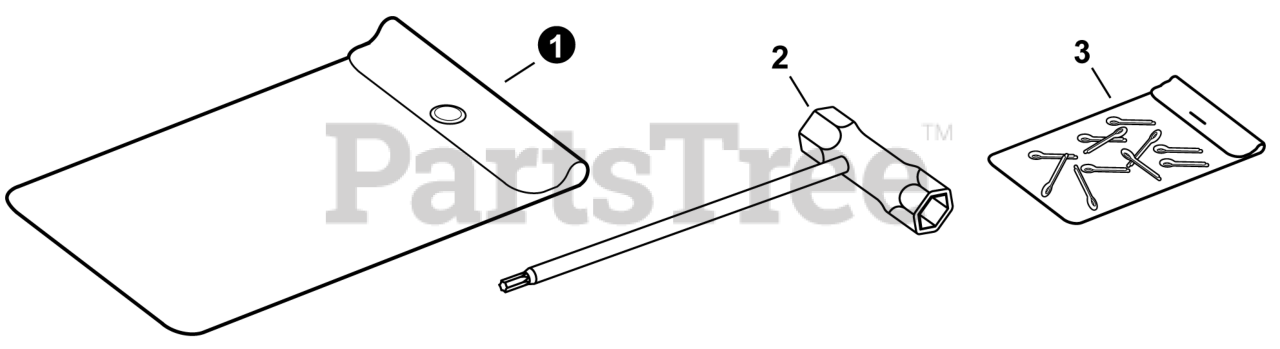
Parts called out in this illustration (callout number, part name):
1	BAG, TOOL
2	T-WRENCH
3	PIN, COTTER 2x22
